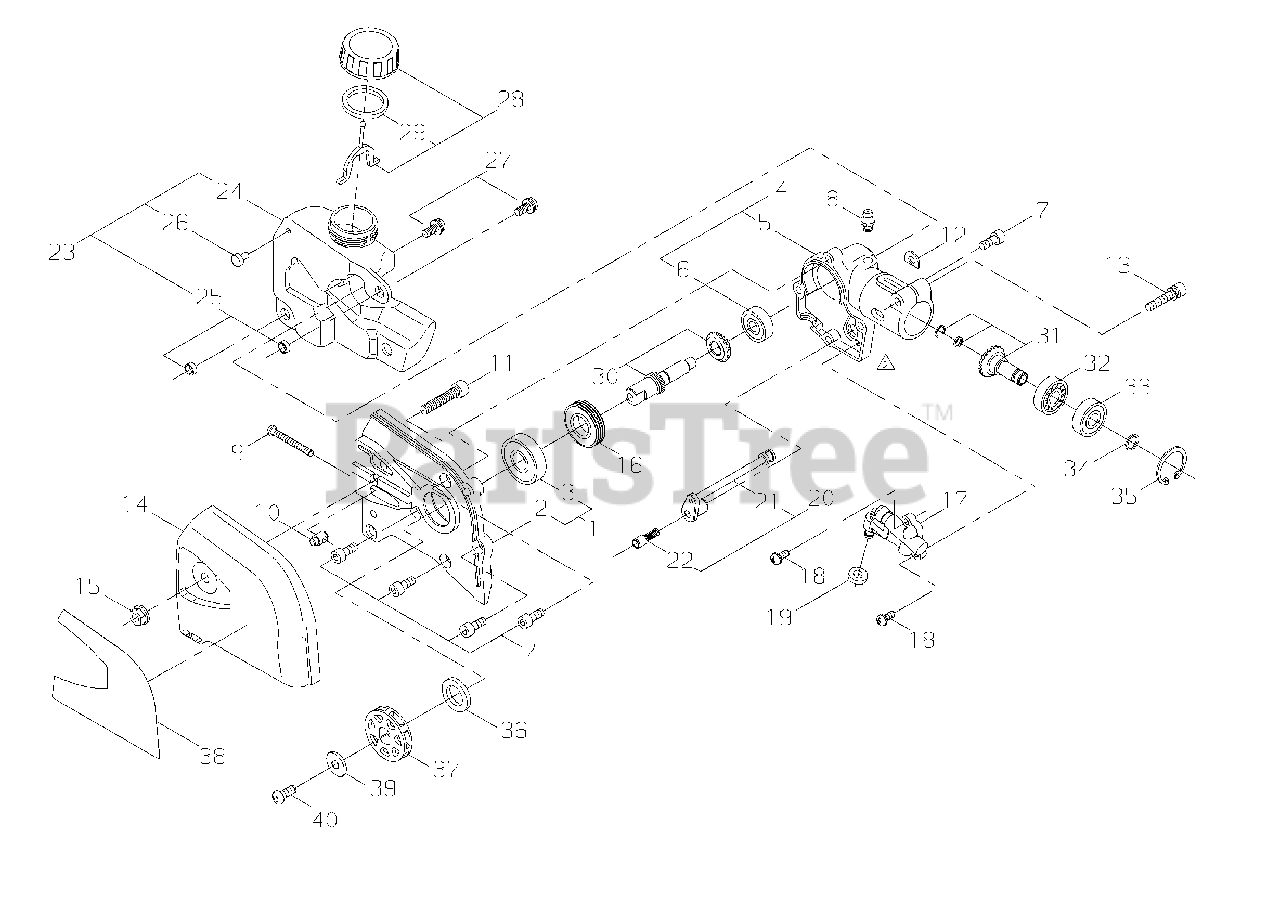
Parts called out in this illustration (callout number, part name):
1	GEAR CASE ASSY - LEFT
2	GEAR CASE ASSY - LEFT
3	BEARING, BALL - 6001DDU
4	GEAR CASE ASSY - RIGHT
5	GEAR CASE ASSY - RIGHT
6	BEARING, BALL - 627ZZ
7	SCREW - 5X12
8	FITTING, GREASE
9	SCREW - 4X35
10	TENSIONER, CHAIN
11	SCREW - 6X30
12	SHIM
13	SCREW - 5X25
14	COVER
15	NUT - 6 -- FLANGE
16	GEAR - WORM
17	AUTO-OILER ASSY
18	SCREW - 4X10
19	GASKET, PUMP
20	OIL TUBE ASSY
21	PIPE - OIL
22	FILTER
23	OIL TANK ASSY
24	TANK, OIL
26	VALVE, OIL
27	SCREW - 5X12
28	OIL CAP ASSY
29	GASKET, CAP
30	GEAR - SHAFT
31	GEAR - BEVEL
32	BEARING, BALL - 609
33	BEARING, BALL - 609ZZ
34	RING, RETAINING
35	RING, RETAINING - 24
36	COLLAR
37	SPROCKET
38	LABEL - CAUTION
39	WASHER - 6
40	SCREW - 6X14
